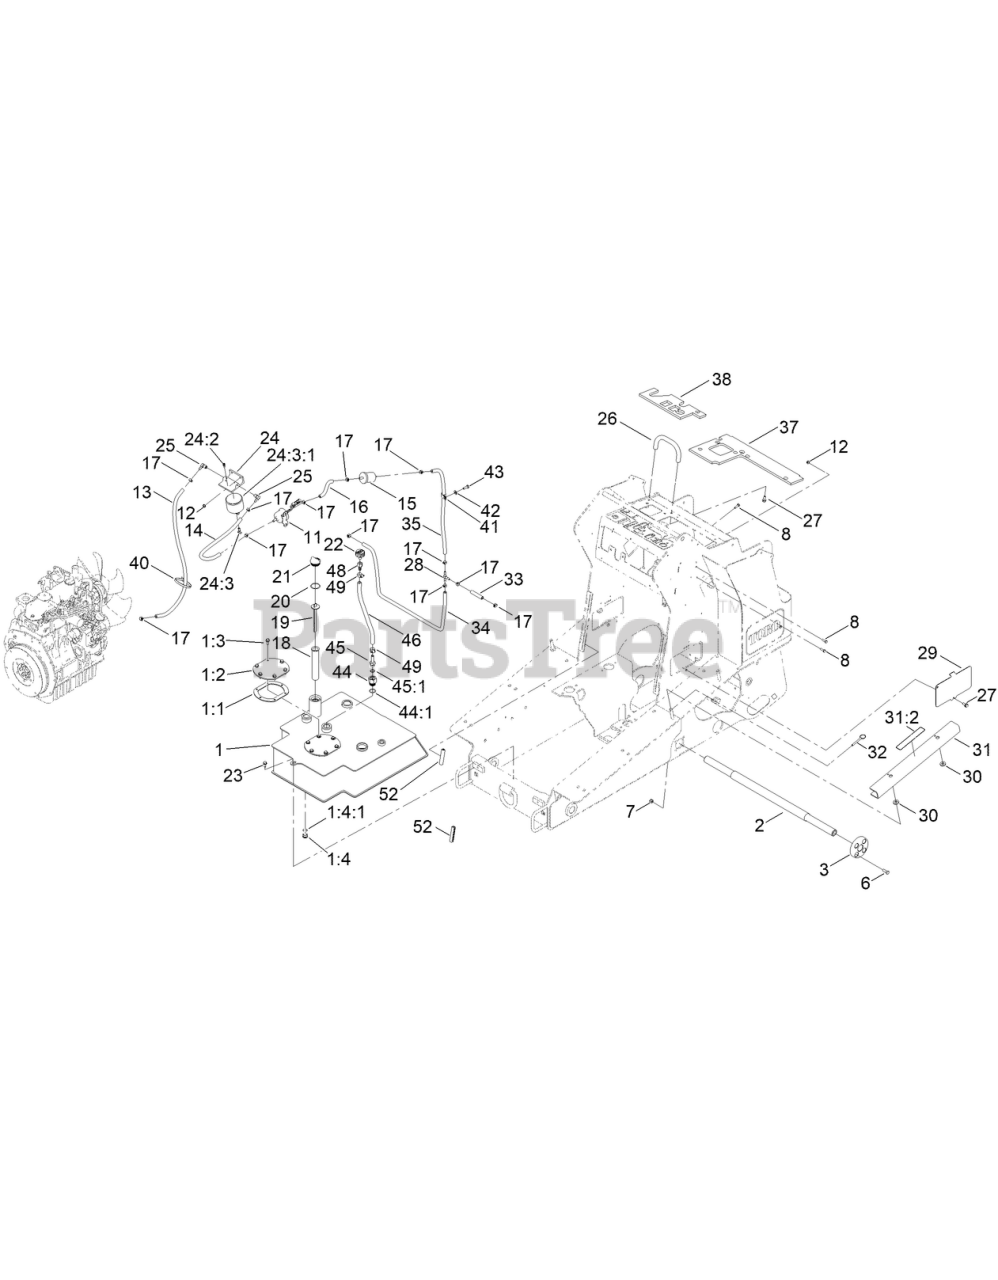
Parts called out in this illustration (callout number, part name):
1	TANK-HYD
1:1	GASKET-COVER, ACCESS
1:2	COVER-TANK
1:3	SCREW-HHF
1:4	PLUG-HEX
1:4:1	O-RING
2	SHAFT-TRACK
3	HUB-SHAFT
6	SCREW-HH
7	NUT-LOCK, NI
8	SCREW-HH
11	PUMP-FUEL, ELECTRIC
12	NUT-HF
13	HOSE-FUEL
14	HOSE-FUEL
15	FILTER-FUEL
16	HOSE-FUEL
17	CLAMP-HOSE
18	FILTER-SCREEN
19	DIPSTICK
20	O-RING
21	PLUG-PLASTIC
22	BREATHER
23	SCREW-THD ROLL, HWH
24	FILTER HEAD ASM
24:2	VENT-AIR
24:3	ELEMENT-SPIN ON
24:3:1	VALVE-DRAIN
25	FITTING-HYD, 90
26	BAR-REFERENCE
27	SCREW-HHF
28	FITTING-TEE, BARBED
29	PLATE-COVER, ACCESS
30	WASHER-NEOPRENE
31	ARM-LOCKING
31:2	DECAL-DANGER
32	PIN-COTTERLESS
33	HOSE-FUEL
34	HOSE-FUEL
35	HOSE-FUEL
37	FOAM-HEAT SHIELD
38	FOAM-HEAT SHIELD
40	TIE-CABLE
41	CLAMP-R
42	WASHER-FLAT
43	SCREW-HH
44	FITTING-STRAIGHT
44:1	O-RING
45	FITTING-STR
45:1	O-RING
48	FITTING-FEMALE, BARBED
49	CLAMP-HOSE
